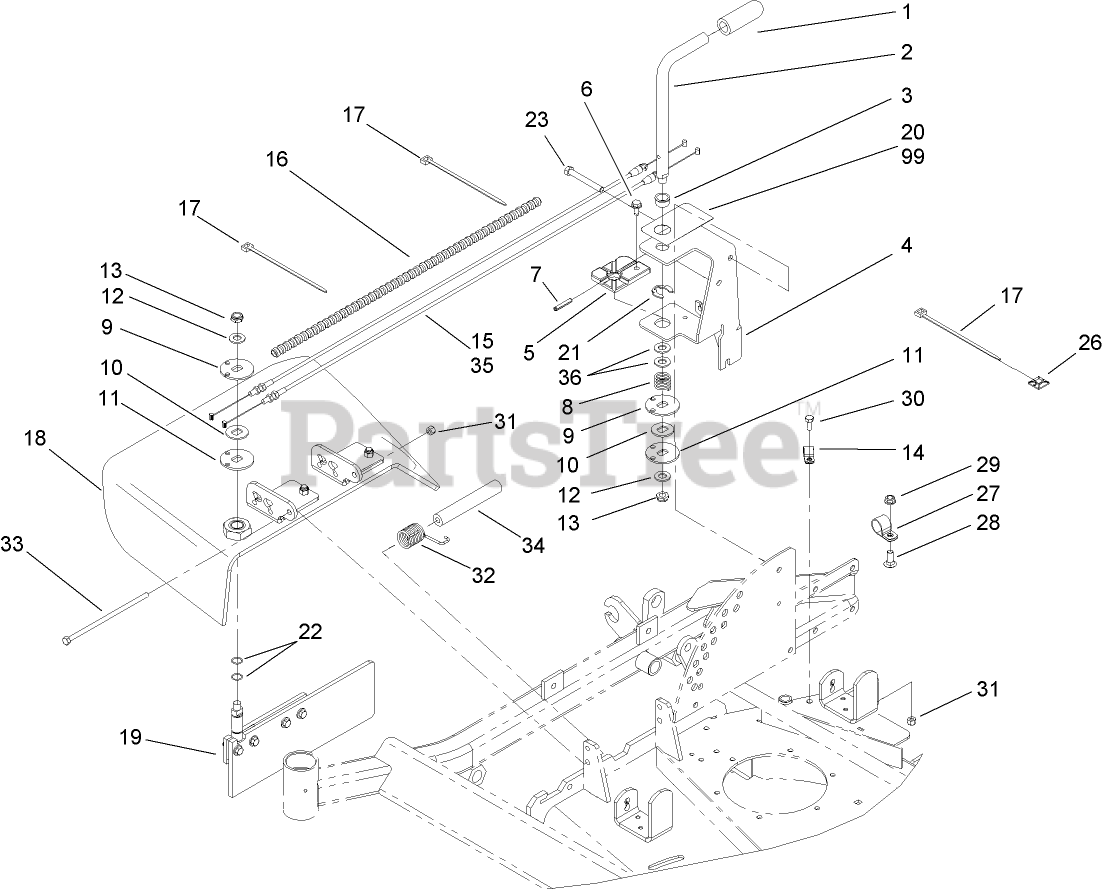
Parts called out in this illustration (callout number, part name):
2	HANDLE
3	BEARING-FLANGE
4	BRACKET-MOUNT
5	BLOCK-DETENT
6	SCREW-HWHTF
7	PIN-ROLL
8	SPRING-COMPRESSION
9	PULLEY-TOP
10	PULLEY-MIDDLE
11	PULLEY-BOTTOM
12	WASHER-FLAT
13	NUT-LOCK, NI
14	CLAMP-R
15	CABLE (Used on 48, 52 and 62 Inch Decks only)
16	TUBE-CONVOLUTED
17	TIE-CABLE
18	RUBBER DEFLECTOR ASM
19	DOOR ASM
20	DECAL-GATE, CHUTE
21	RING-RETAINING
22	O-RING
23	SCREW-HH
26	MOUNT-TIE, CABLE
27	CLAMP-R
28	BOLT-CARR
29	NUT-HHF, WHIZ
30	SCREW-HH
31	NUT-LOCK, NI
32	SPRING-TORSION
33	SCREW-HH
34	SPACER
35	CABLE (Used on 72 Inch Deck only)
36	WASHER-FLAT
99	DECAL-GATE, CHUTE (CE)
